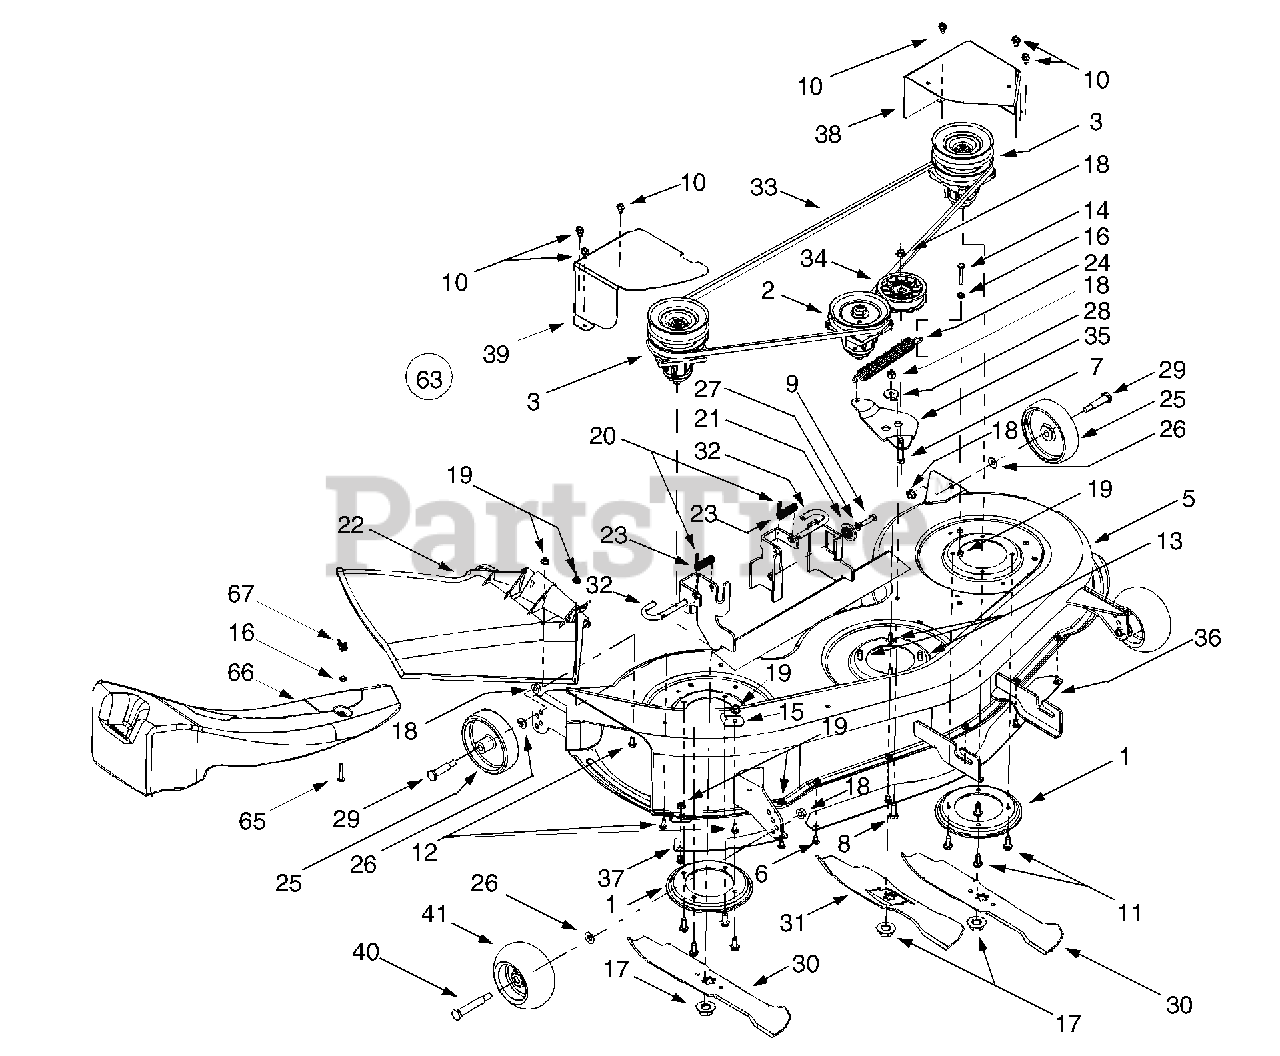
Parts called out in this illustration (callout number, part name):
3	Double Pulley Spindle Assembly
5	46-inch Deck Shell
7	Hex Cap Screw, 3/8-16 x 1.75
8	Hex Cap Screw, 3/8-16 x 1.0
9	Hex Cap Screw, 5/16-18 x 1.25
10	Self Tapping Screw,1/4-20 x .5
11	Self Tapping Screw, 5/16-18 x .875
12	Hex Cap Screw, 1/4-20 x .62
13	Self Tapping Screw, 5/16-18 x .75
14	Hex Cap Screw, 1/4-20 x 1.25
15	Retainer Hook
16	Center Lock Nut, 1/4-20
17	Hex Flange Nut, 5/8-18
18	Flange Lock Nut, 3/8-16
19	Hex Flange Lock Nut, 1/4-20
20	Internal Cotter Pin, .072 x 1.12
21	Deck Adjustment Gear
22	Side Discharge Chute Assembly
23	Compression Spring, .406 x .531 x 1.75
24	Extension Spring, .91 x 7.33
25	Deck Wheel, 5 x 1.38
26	Bell Washer, .401 x .87 x .063
27	Lock Washer, 5/16
28	Shoulder Spacer, .625 x .169
29	Shoulder Spacer, .498 x 1.53
30	Three-in-one Blade, Star Center, 16.28
31	Three-in-one Blade, Star Center, 14.88
32	Deck Release Pin
33	Deck Belt
34	Flat Idler Pulley, 3.5 OD
41	Deck Wheel, 5
66	Mulch Plug (if so equipped)
67	Wing Nut, 1/4-20 (if so equipped)
